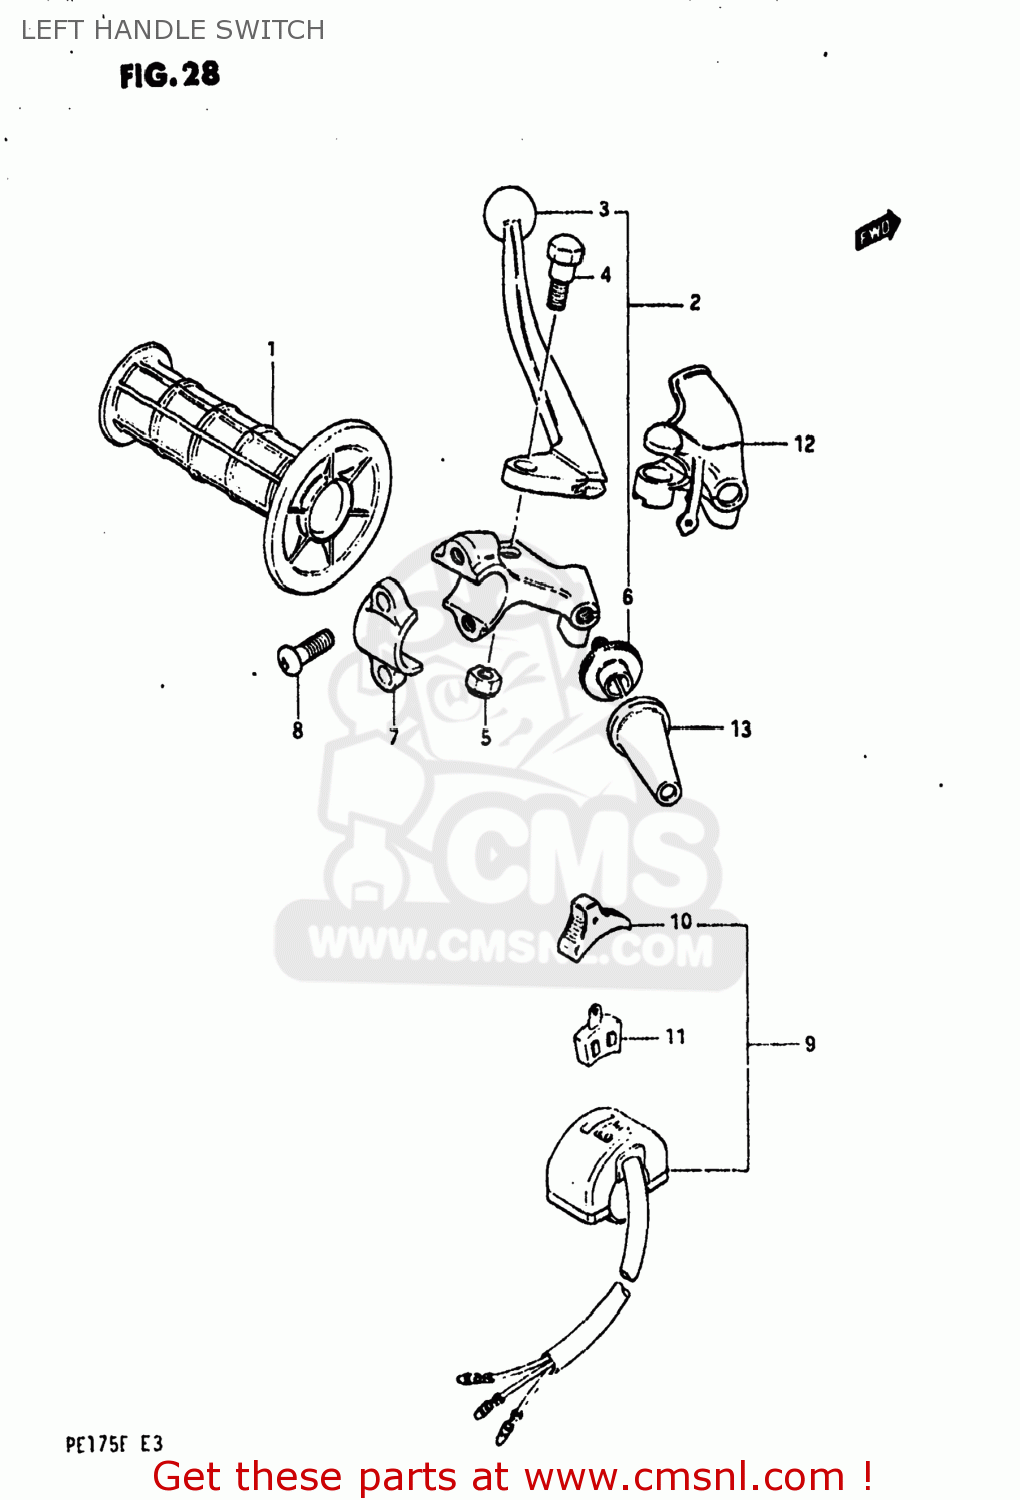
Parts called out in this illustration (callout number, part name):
1	GRIP,LEFT
2	LEVER ASSEMBLY,CLUTCH
3	LEVER,CLUTCH
4	BOLT,LEVER
5	NUT 6MM
6	ADJUSTER,CABLE
7	BRACKET,LEVER
8	SCREW
9	SWITCH,DIMMER
10	KNOB,LIGHTING & DIMMER
11	BLOCK,LIGHTING/DIMMER
12	COVER,BRAKE LEVER
13	BOOT,CLUTCH CABLE
